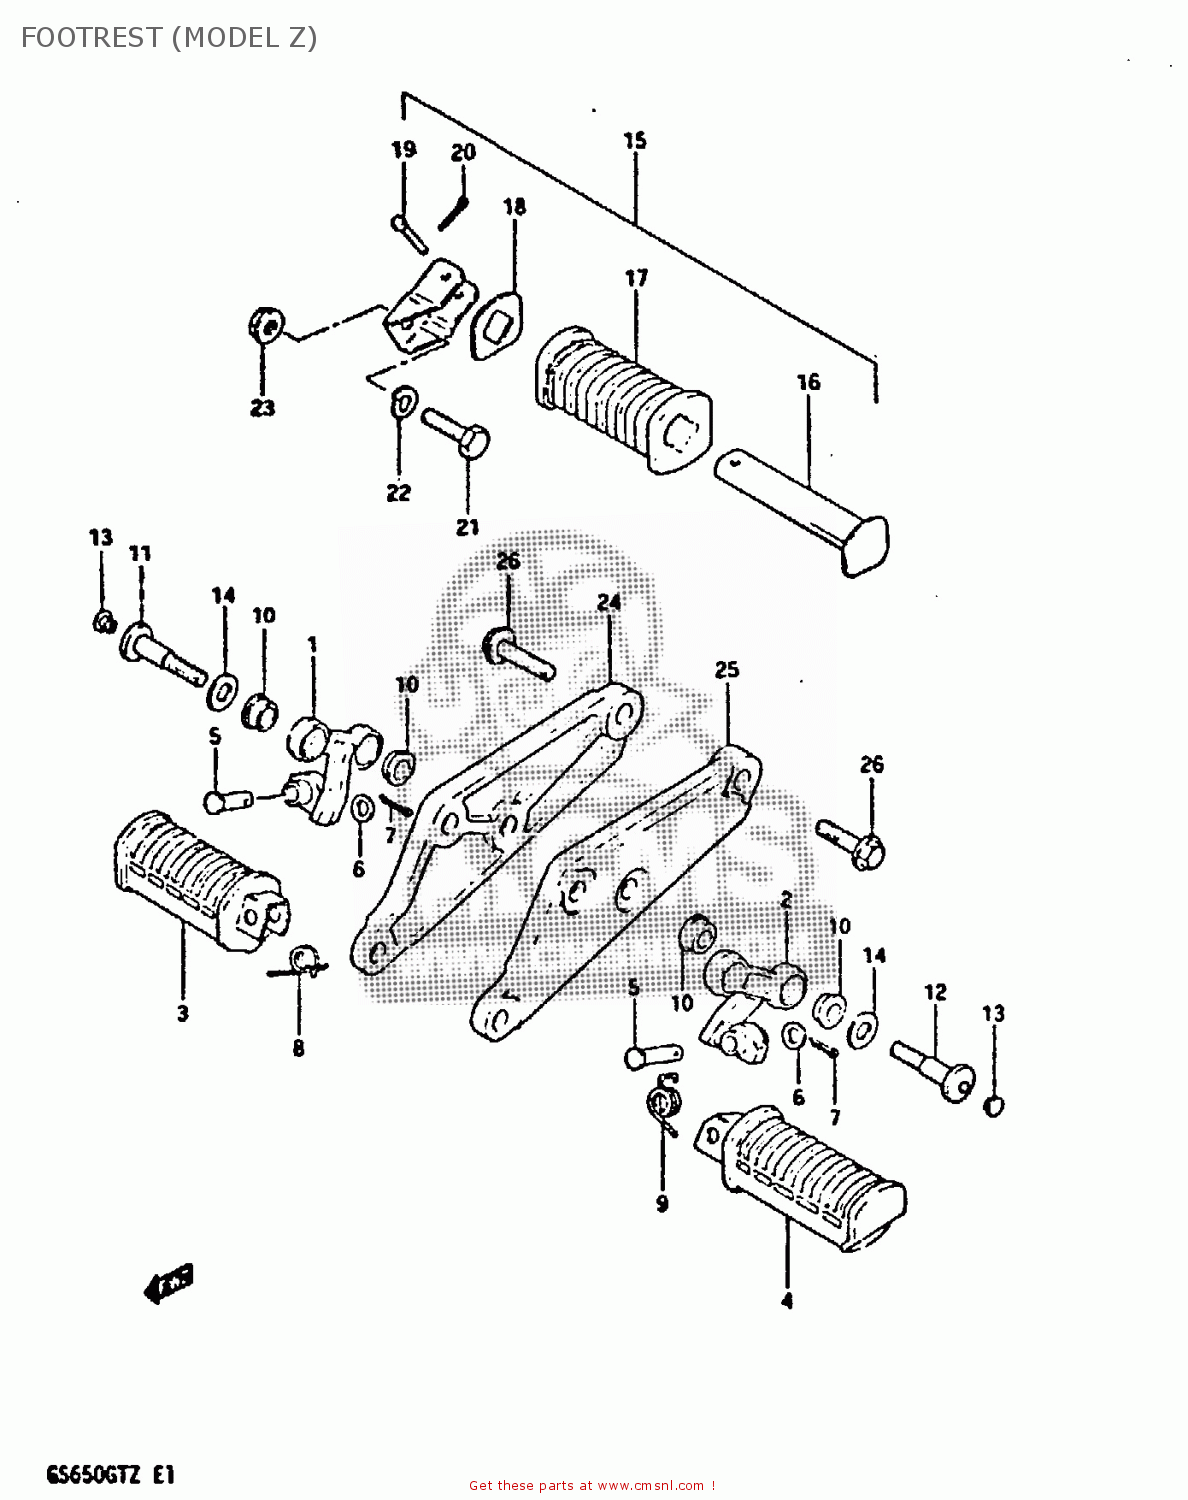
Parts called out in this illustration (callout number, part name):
1	BAR,FRONT FOOTREST
2	BAR,FRONT FOOTREST,LEFT
3	RUBBER,FOOTREST
4	FOOTREST
5	PIN
6	WASHER
7	PIN
8	SPRING
9	SPRING
10	BUSH
11	BOLT
12	BOLT
13	CAP
14	WASHER(10.5X28X2.3)
15	FOOTREST ASSY,PILLION,R
16	BAR,REAR FOOTREST,LEFT
17	RUBBER,PILLION FOOTREST
18	WASHER,FOOTREST RUBBER
19	PIN
20	PIN
21	BOLT,M10X1.25X
22	LOCK WASHER
23	NUT
24	BRACKET,MUFFLER,RIGHT
25	BRACKET,MUFFLER,LEFT
26	BOLT
